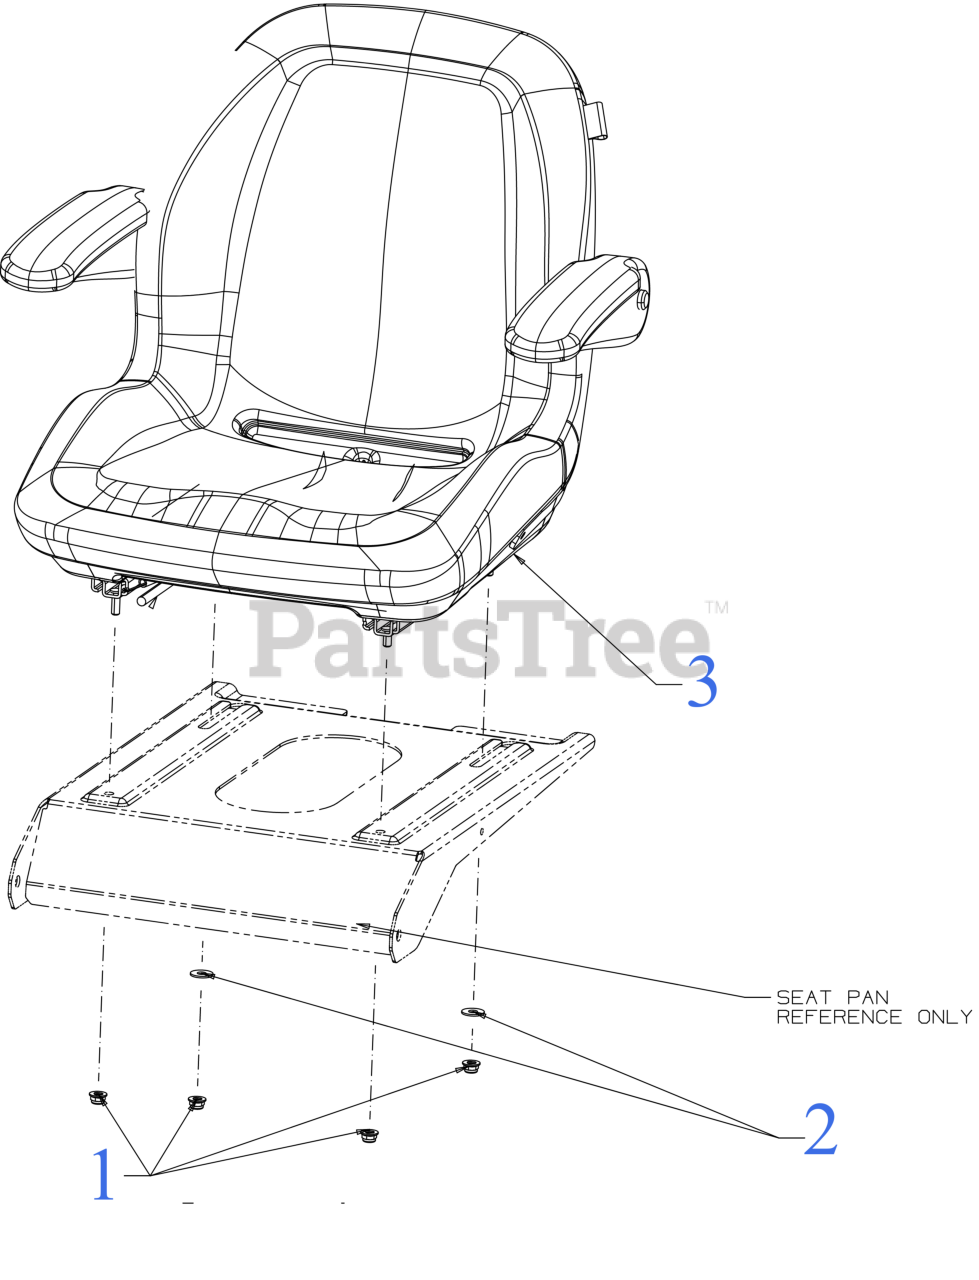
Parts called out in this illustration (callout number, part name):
1	FLANGE LOCK NUT 5/16-18
2	FLAT WASHER
3	18.5" SEAT (W/SLIDES/ARM)
